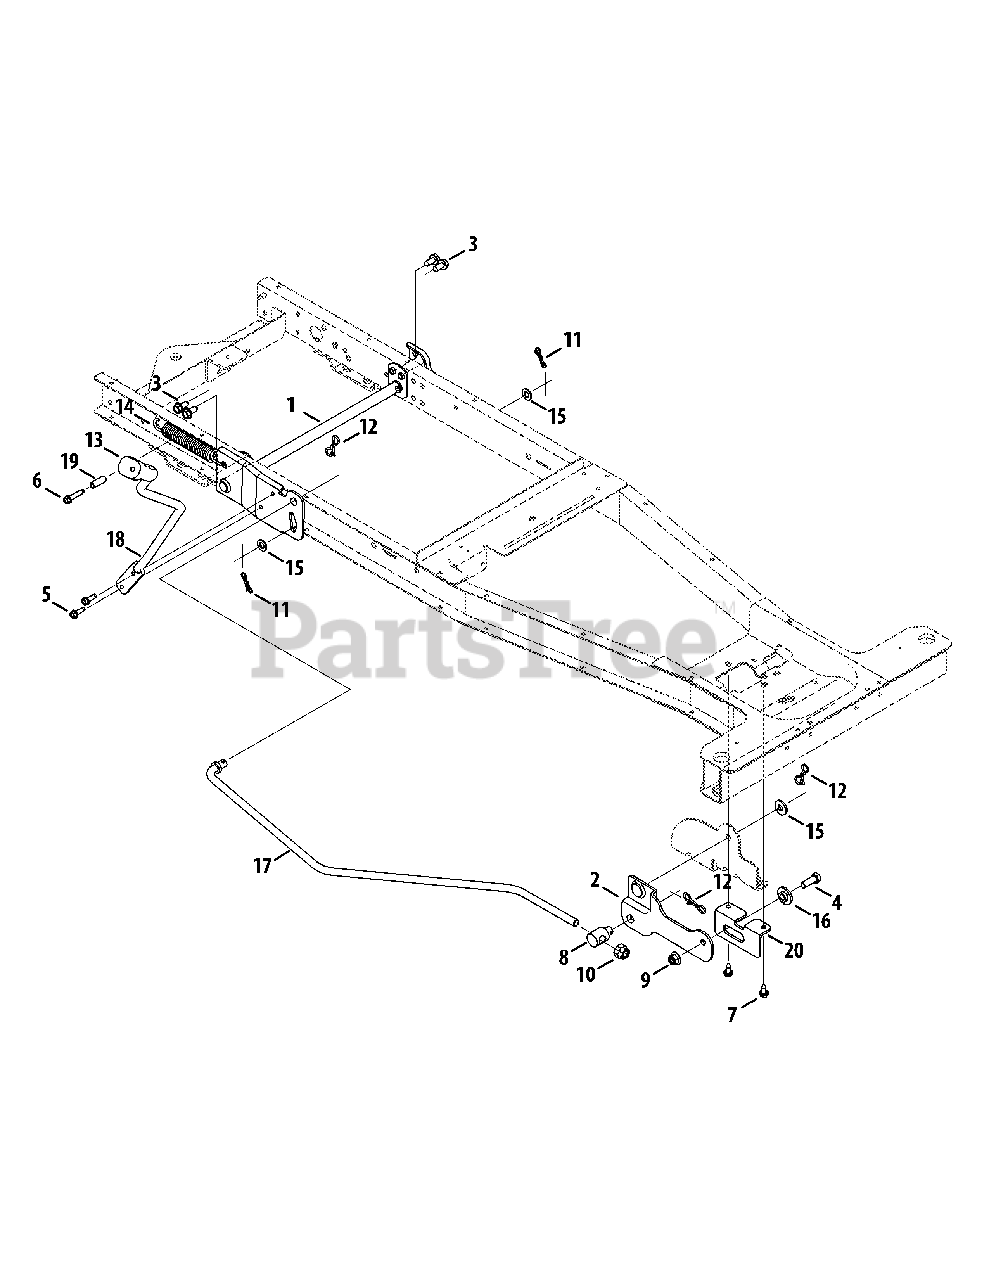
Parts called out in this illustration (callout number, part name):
1	Lift Assembly Shaft
2	Front Hanger Bracket Assembly
3	Tap Screw, 5/16-18, .750
4	Hex Head Screw, 3/8-16, 1.00
5	Tap Screw, 1/4-20, 0.750
6	Tap Screw, 1/4-20, 1.250
7	Tap Screw, 1/4-20 X .625
8	Ferrule, .50 X .50
9	Flange Lock Nut, 3/8-16
10	Flex Lock Nut, 1/2-13
11	Bow-Tie Cotter Pin, 72
12	Bow-Tie Cotter Pin, 91
13	Grip Handle, 1/2
14	Extension Spring, .85 OD X 5.915 LG
15	Flat Washer, .406 X .875 X .059
16	Shoulder Spacer, .625 ID X .169
17	Lift Link Rod
18	Deck Lift Rod
19	Spacer, .260 x .375 x 1.030 LG
20	Front Deck Mounting Bracket
